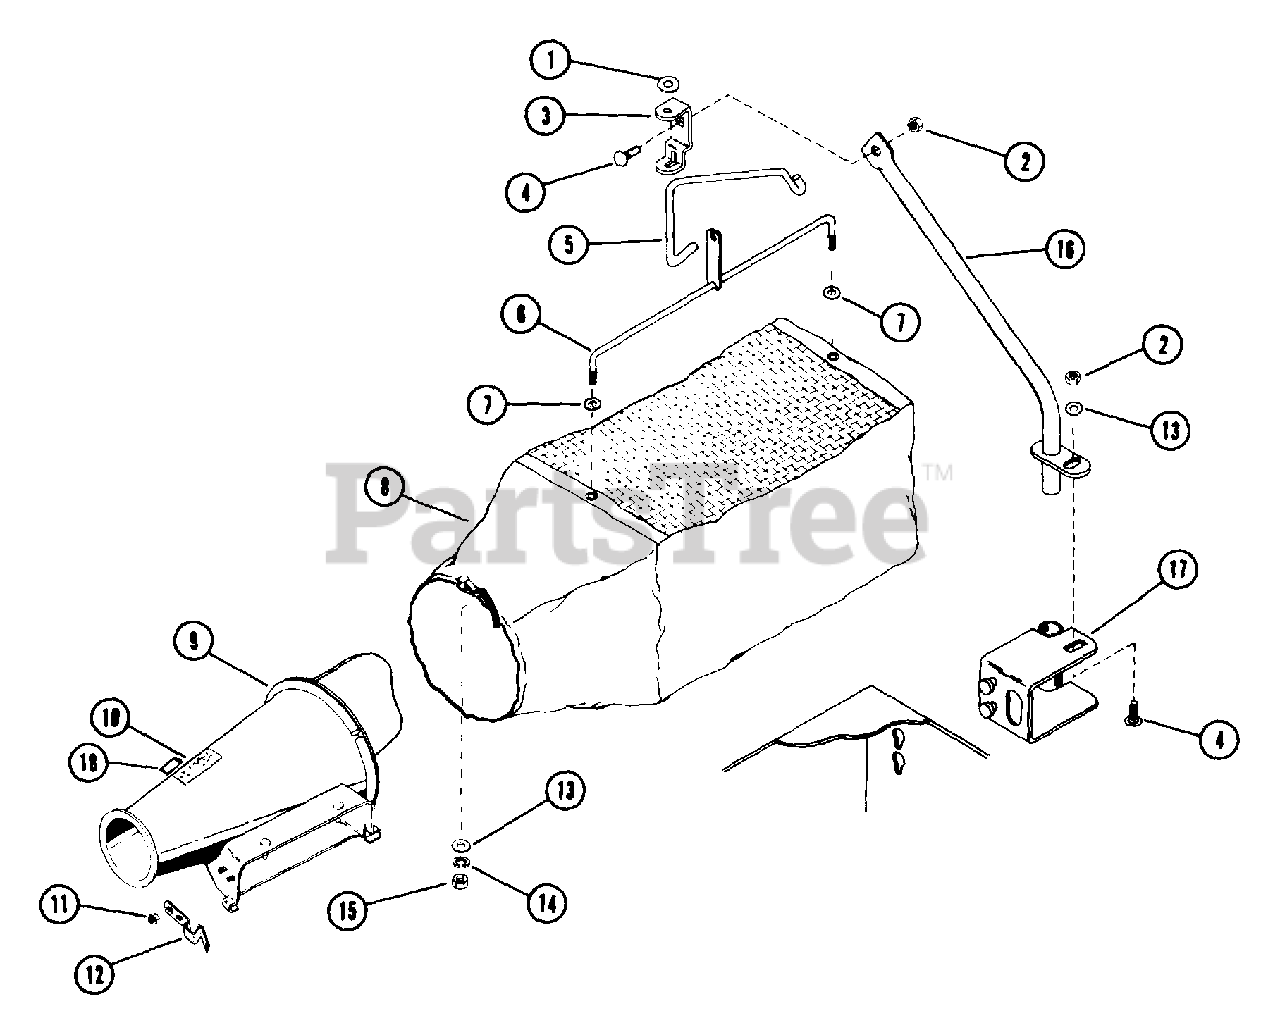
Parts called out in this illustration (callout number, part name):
1	WSHR-FL-STL .323X.625X.062 PL
2	NUT-LK-CTR .375-16 GR A PL
3	STABILIZER BRACKET
4	BLT-RDHDSQNK .38-16X.75 SHT PL
5	STABILIZER ROD
6	CROSS BAR
7	WSHR-FL-STL .38X.875X.083 PL
8	GRASS CATCHER BAG
9	CONE ASSEMBLY
10	CAUTION LABEL
11	NUT-LK-FLG .250-20 PL
12	SPRING, FLAT
13	WSHR-FL-STL.406X.812X.065PL
14	WSHR-LK .375X.115 HVY PL
15	NUT-HEX .375-16
16	SUPPORT BAR
17	SUPPORT BAR BRACKET
18	PATENTS PENDING LABEL
